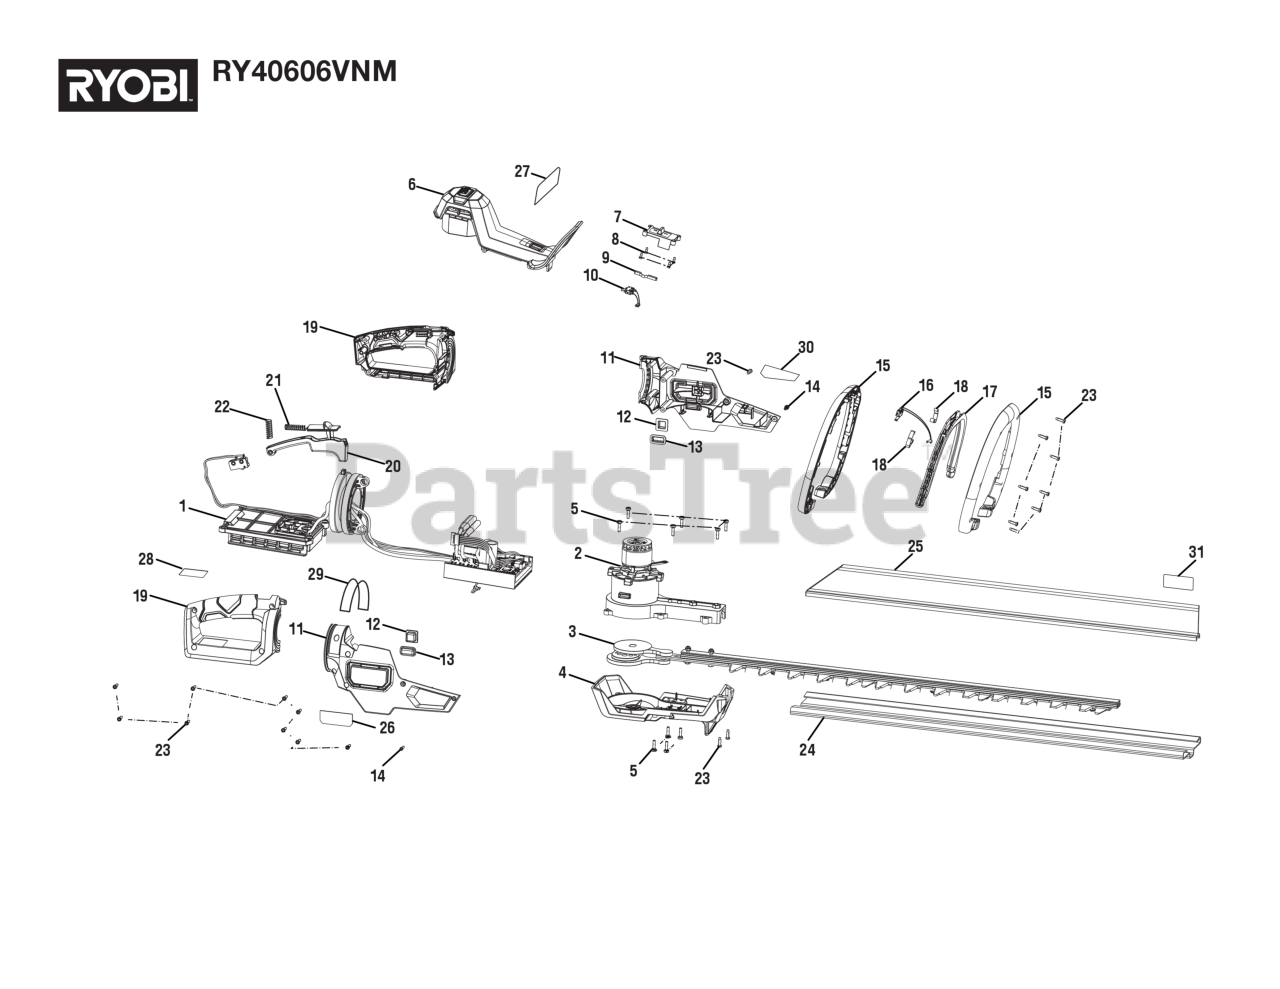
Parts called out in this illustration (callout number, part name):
1	Battery Foot and Rear Switch Assembly
2	Motor and Gear Box Assembly
3	Blade Assembly
4	Gearbox Cover Assembly
5	Screw, T25, M4X0.7, Low Carbon Steel
6	Motor Cover Assembly
7	Speed Button Assembly
8	Screw (M3 x 8 mm, Pan Hd., Pan Hd)
9	Spring Plate
10	Speed Switch Assembly
11	Motor Housing Assembly
12	Rubber Plate
13	Rubber Plate
14	Screw (M3 x 12 mm)
15	Front Handle Cover Assembly
16	Front Handle Switch Assembly
17	Front Handle Trigger
18	Spring Plate
19	Rear Handle Assembly
20	Lock-Off Button Spring
21	Lock-Off Button Spring
22	Trigger Spring
23	Screw (M4 x 14 mm, T15 Torx Pan Hd.))
25	Hedge Sweep Assembly
26	Data Label
27	Icon/Danger/Warning Label
29	Rotating Handle Label
30	Warning Label
31	Warning Label
